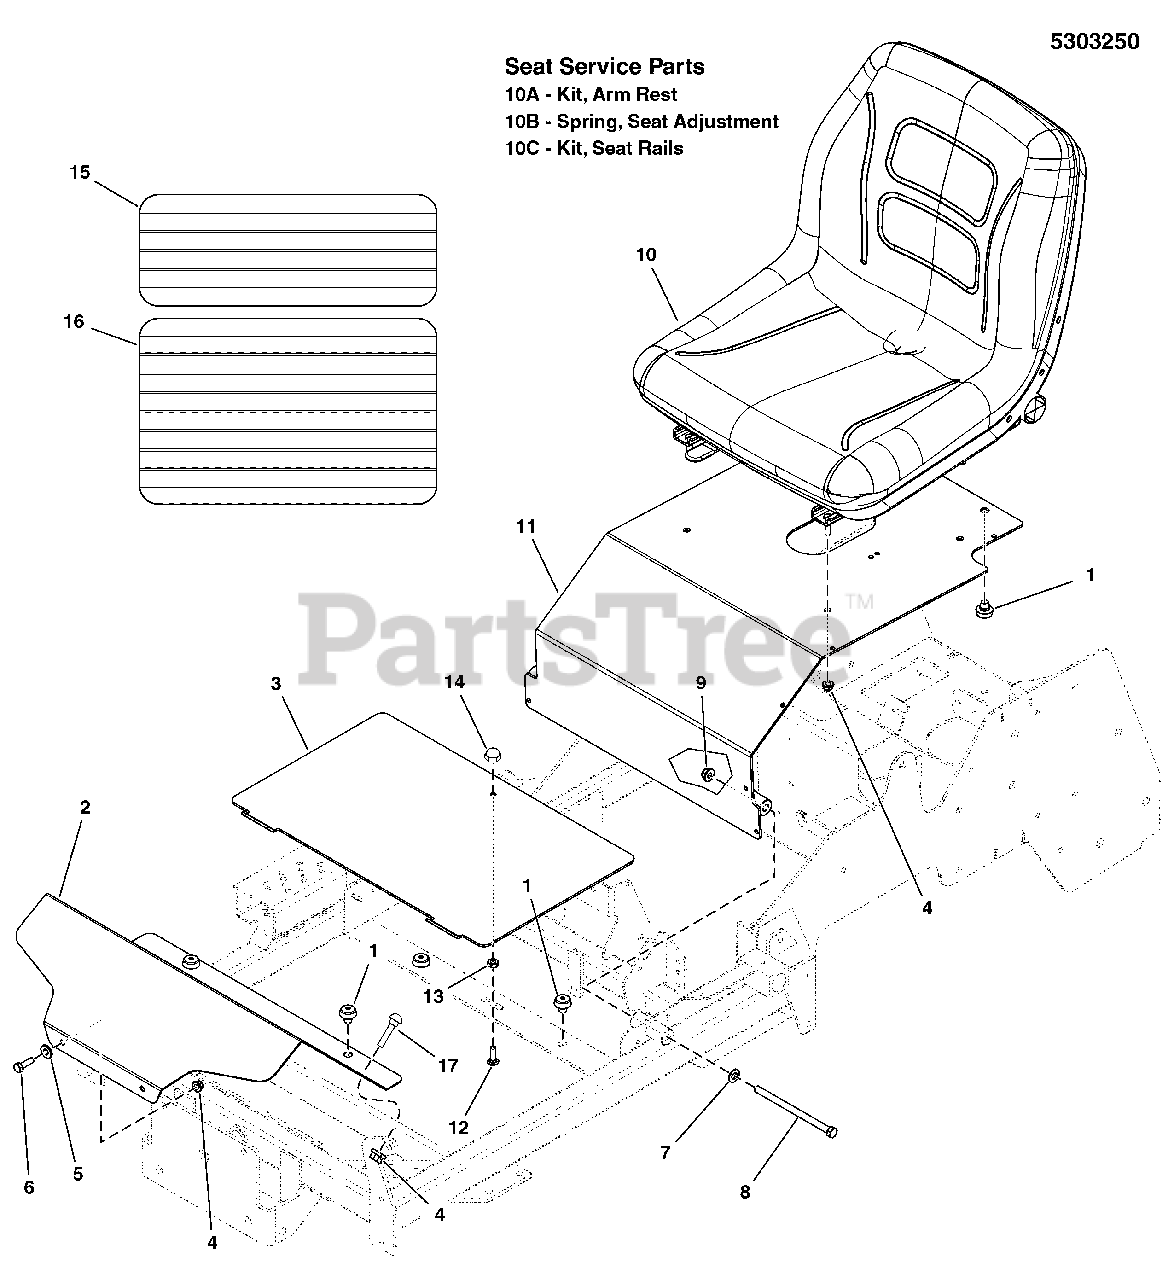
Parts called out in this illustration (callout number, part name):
1	MNT, VBRTN, RBBR
2	PLATE, FLOOR PAN, RIDGID IS600Z - ORG
3	PLATE, FLOOR PAN, REMOVABLE. IS600 - ORG
4	NUT, 5/16-18 HEX NYLOCK FLANGE
5	WASHER, 5/16 F436 FLAT
6	BOLT, 5/16-18 X 1 GD5 YZ
7	WASHER, 3/8 SAE
8	BOLT, 3/8-16 X 6 GD5 YZ
9	NUT, 3/8-16 HEX NYLOCK FLANGE
10	SEAT, NO ARM REST
10A	ARMREST KIT
10B	SPRING, EXTENSION, SEAT ADJUSTMENT (BLK OR SLVR)
10C	SEAT RAIL, KIT, RH AND LH
11	ASSM, SEAT PLATE W/DECALS - ZTS600 (5409894C)
11	ASSM, SEAT PLATE W/DECALS, CHAMPION XT (5415897C)
12	BOLT, 5/16-18 X 1, CARRIAGE YZ
13	NUT, 5/16-18 HEX JAM
14	ACORN NUT, 5/16-18 S/S
15	SAFETY WALK, FLOOR REST, 6.00 X 16.00
16	SAFETY WALK, FLOOR PLATE, S50X, 10X16
17	BOLT, 5/16-18 X 1, CARRIAGE
